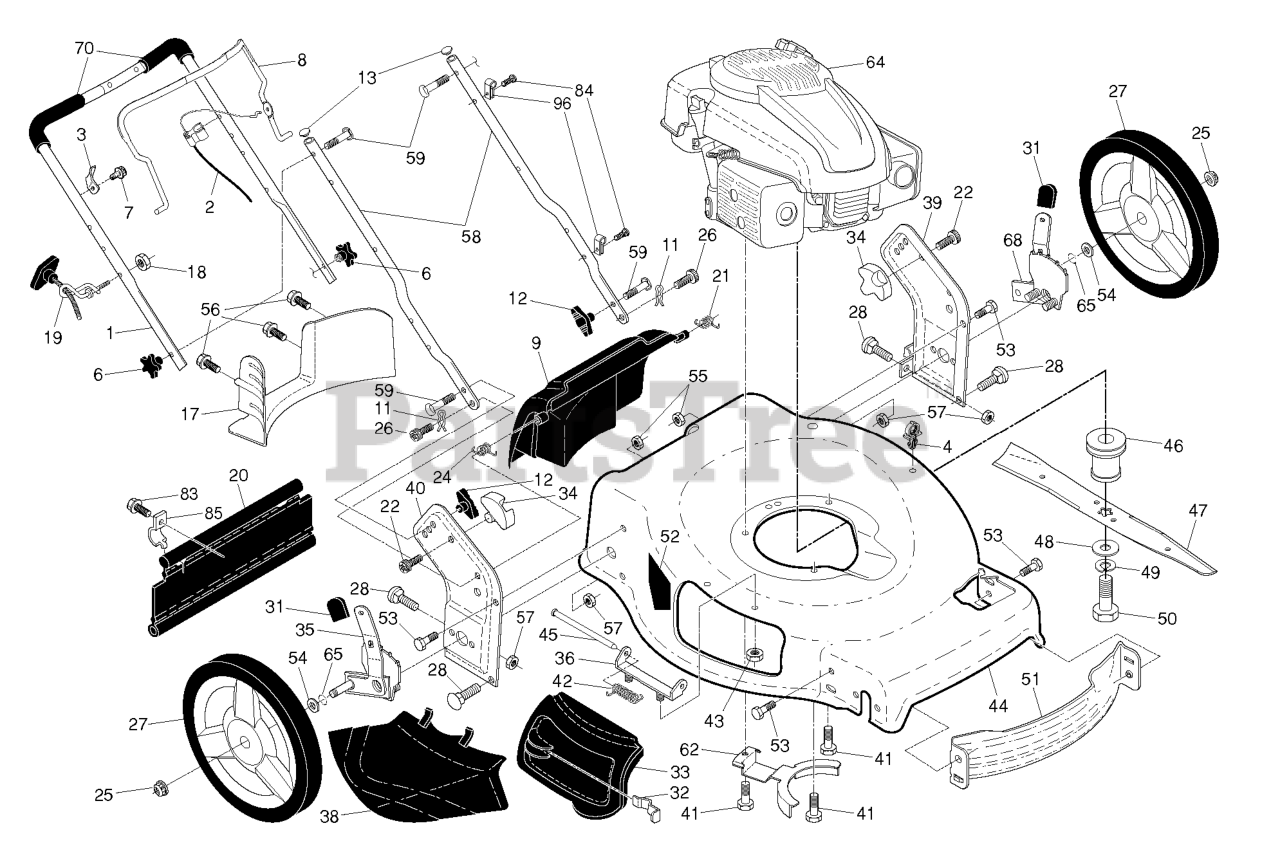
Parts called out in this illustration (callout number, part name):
1	HANDLE.ASM.GRY.W/GRIP
2	CABLE.MZR.FGD.PLUS
3	BRACKET.UPSTOP.RT
6	KNOB.HANDLE.PLASTIC.STAR.BLACK
8	BAIL.MZR.EZ2.DSTR.22+.ORG.E
9	DOOR.REAR.ASM.22+.HUSQ.FG/RGD
11	COTTER.HAIRPIN.DOOR/HANDLE.PIV
12	KNOB, DEFLECTOR
13	PLUG.PLASTIC.7/8".14-20.GAUGE
17	BAFFLE.22PLUS.FGD.REAR.
18	NUT
19	RB GUIDE.ROPE.STD.BLK.ZIN WSL
20	SKIRT.REAR.22PLUS.RGD/FGD.NEW
21	SPRING.LH.BLACK
22	SCREW.PAN.HEAD.#10
24	SPRING.RH.GRAY
25	NUT.HEX.FLANGE.3/8-16.LOCKNUT
26	SCREW,DOOR/HANDLE.PIVOT
27	WHEEL ASSY
28	BOLT
31	SELECTOR KNOB
32	LATCH.DOOR.ZINC
33	DOOR.MULCH.22 PLUS.HUSQ.GREY
34	BRACKET.GRASSBAG.ATTACHING.BLK
35	ADJUSTER.ASM.9POS.HW.R/R
36	BRACKET.ASM.HINGE.21.FWGD.
38	DEFLECTOR.CLIPPING.22.BLACK
39	BRACKET.HANDLE.LT.22+.W/DP.GRE
40	RP.BRACKET.ASM.HANDLE.RT.22+.
41	BOLT 3/8-16X1-1/8
42	SPRING.TORSION
43	NUT.HEX.FLANGE.1/4
45	ROD.HINGE.21
46	ADPTER.BLAD.25M.VS.22PLU.STAR
47	BLADE.22PLUS
48	WASHER,HARDEN
49	LOCKWASHER
50	SCREW, HEX HD 3/8-24 X 1-3/8
51	BAFFLE.FRONT.22.PLUS
52	DANGER DECAL
53	BOLT.5/16HEX.WHS.HD
54	WASHER.FLAT.1/2
55	NUT.HEX.FLANGE.1/4
56	SCREW.HX.13X.750
57	NUT.FLANGE.5/16
58	HANDLE.LOWER.22+BT.2PC.GRY
59	BOLT, HANDLE 5/16-18X1.75
62	BRACKET.ENG/BELTKEEPER
65	O-RING..070X.487.NEOPRENE
68	ADJUSTER.ASM.9POS.HW.R/L
70	GRIP.HANDLE.FOAM.WIDE.(1 SIDE)
83	TAPPING SCREW
84	FASTENER.PUSH.O.250X0.783
85	BRACKET.SKIRT.22+.BZP
96	CLIP.CABLE.BLK
